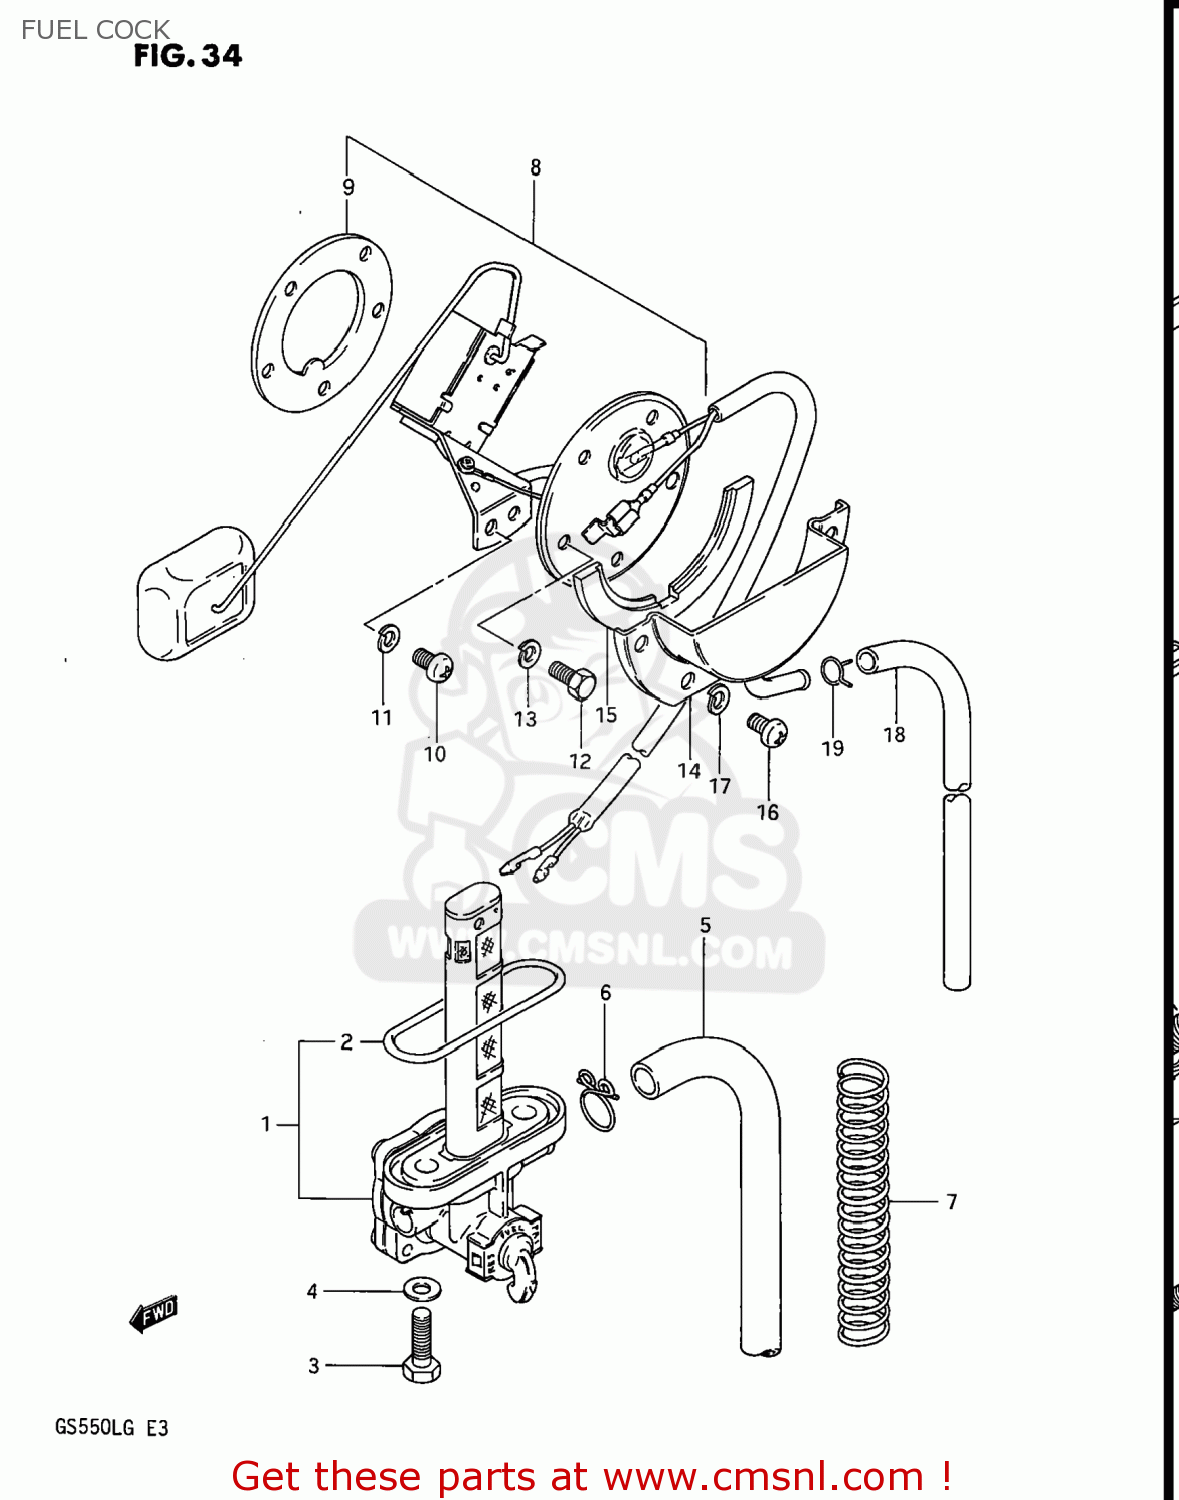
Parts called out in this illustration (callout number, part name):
1	COOK ASSY,FUEL
2	O RING
3	BOLT(6X20)
4	GASKET
5	HOSE
6	CLIP
7	SPRING
8	GAUGE ASSEMBLY,FUEL LEVEL
9	GASKET,FUEL LEVEL GAUGE (NAS)
10	SCREW 5X10
11	LOCK WASHER
12	BOLT
13	LOCK WASHER
14	PLATE,FUEL DRAIN
15	GASKET (NAS)
16	SCREW
17	LOCK WASHER
18	HOSE,FUEL
19	CLIP
